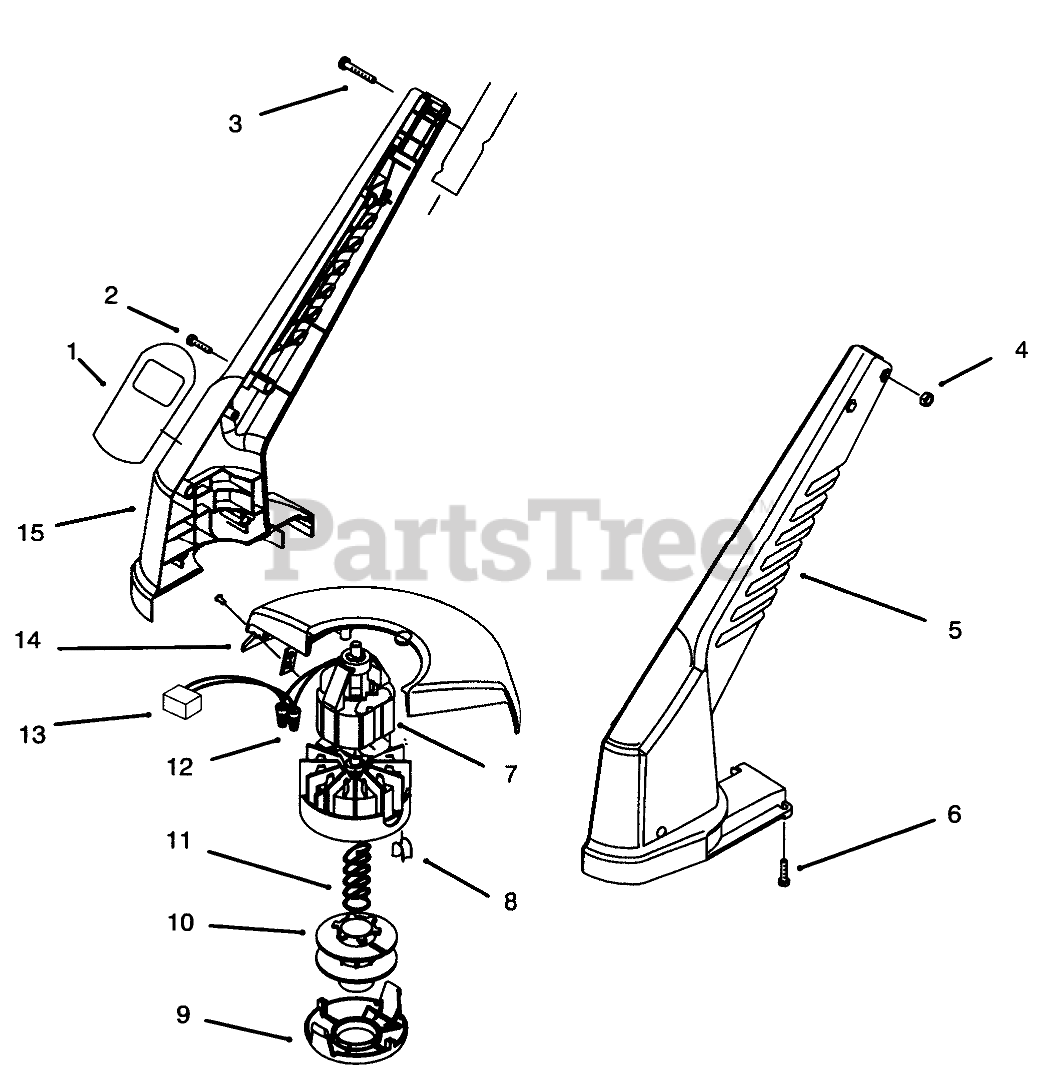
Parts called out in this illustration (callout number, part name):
1	Decal-25CM Trimmer
2	HOUSING RH - TRIMMER, EUO
3	SCREW-PPH
4	NUT-HEX
5	HOUSING LH - TRIMMER
6	Screw
7	Motor Assembly-Trimmer (Incl. Ref. #8)
8	EYELET
10	SPOOL-LARGE
11	SPRING-COMPRESSION
12	CONNECTOR-NUT, WIRE
13	FILTER - RFI
14	SHIELD ASM - SERVICE
15	HOUSING RH - TRIMMER, EUO
